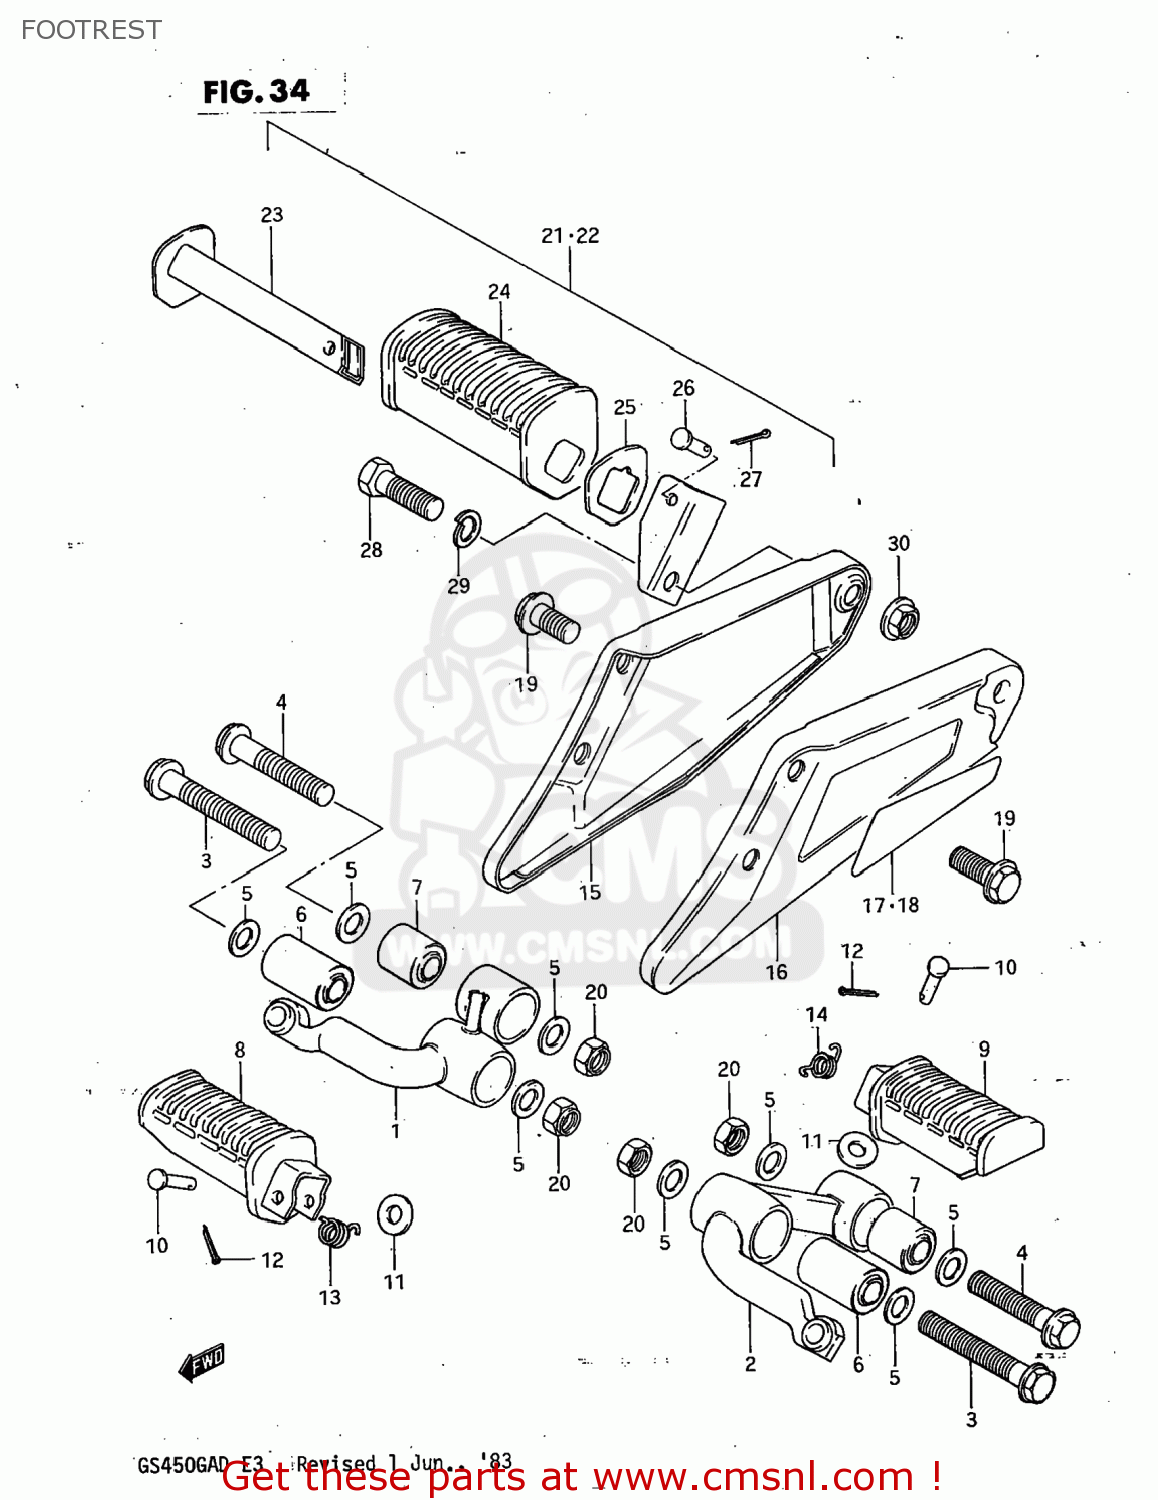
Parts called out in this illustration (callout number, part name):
1	BAR,FRONT FOOTREST
2	BAR,FRONT FOOTREST,LEFT
3	BOLT
4	BOLT
5	WASHER
6	BUSHING(10X23X35)
7	BUSH
8	RUBBER,FOOTREST
9	FOOTREST
10	PIN
11	WASHER
12	PIN 20X20
13	SPRING
14	SPRING
15	BRACKET
16	BRACKET
19	BOLT
20	NUT
21	FOOTREST ASSEMBLY,REAR
22	FOOTREST ASSEMBLY,PILLION
23	BAR,REAR FOOTREST
24	RUBBER,REAR FOOTREST
25	WASHER,REAR FOOTREST RUBBER
26	PIN
27	PIN 20X20
28	BOLT,M10X1.25X
29	LOCK WASHER
30	NUT
